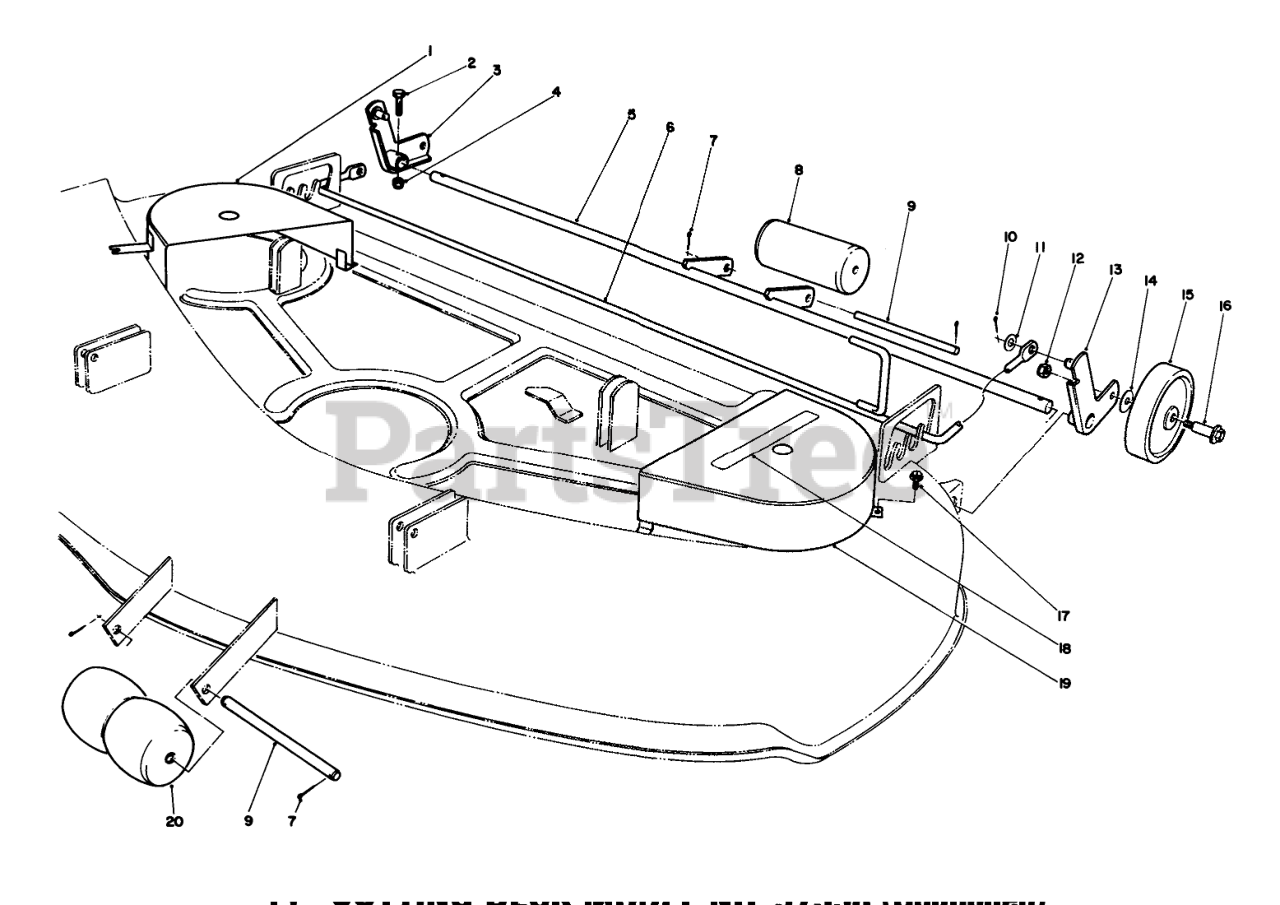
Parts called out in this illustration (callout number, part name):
1	Cover-Spindle R.H.
2	SCREW-HH
3	RH WHEEL BRKT WA B
4	NUT-LOCK, NI
6	Bracket
7	PIN-COTTER
8	ROLLER-DECK
9	ROLLER SHAFT
10	PIN-COTTER
11	WASHER-FLAT
12	NUT-LOCK, NI
13	LH WHEEL BRKT WA B
14	WASHER-THRUST
15	Wheel-6"
16	WHEEL BOLT
17	SCREW-HWHTF
18	DECAL-NO STEP
19	Cover-Spindle
20	ROLLER
